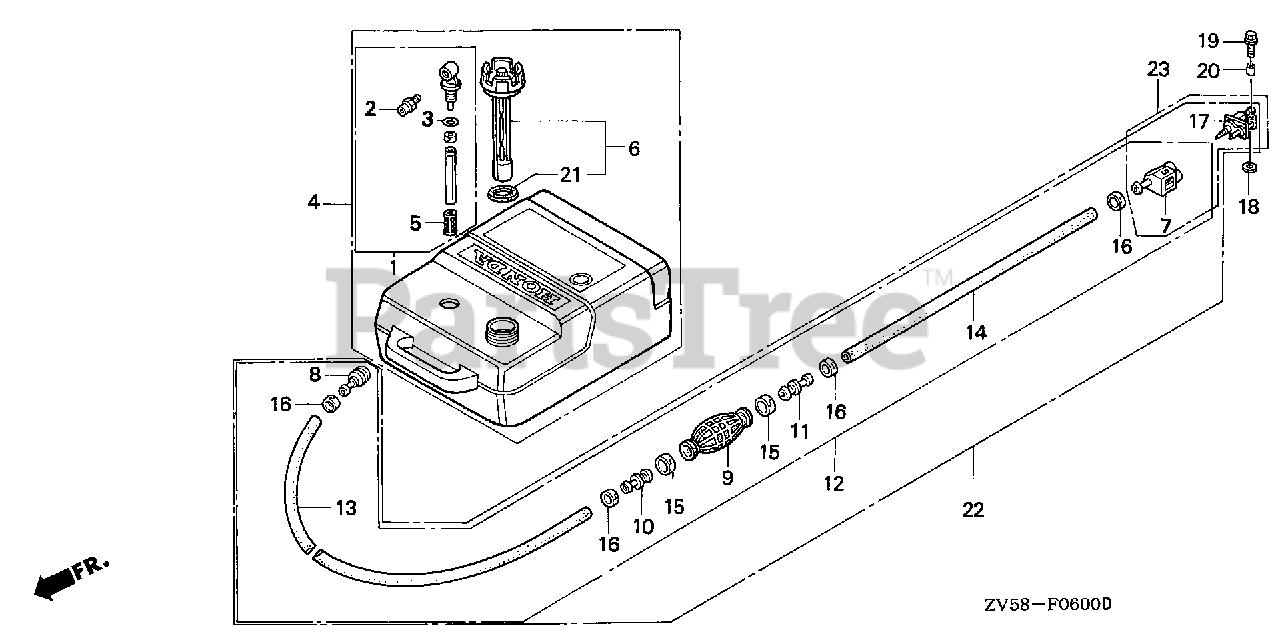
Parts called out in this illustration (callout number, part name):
1	JOINT ASSY., FUEL
2	FITTING, QUICK DISCONNECT
4	TANK ASSY., FUEL
5	FILTER, FUEL
6	CAP, FUEL FILLER
7	CONNECTOR ASSY., FUEL (A)
8	CONNECTOR, FUEL
9	BULB, PRIMER
10	VALVE, IN.
11	VALVE, OUTLET
12	TUBE ASSY., FUEL
13	TUBE, FUEL LONG (7.3X2000)
14	TUBE, FUEL SHORT (6.3X500)
15	BAND, TUBE CLIP (20MM)
16	BAND, TUBE CLIP (12.5MM)
17	CONNECTOR ASSY., FUEL (B)
18	WASHER, PIVOT
19	BOLT, FLANGE (6X20)
20	COLLAR, DISTANCE (6MM)
21	GASKET, FUEL CAP
